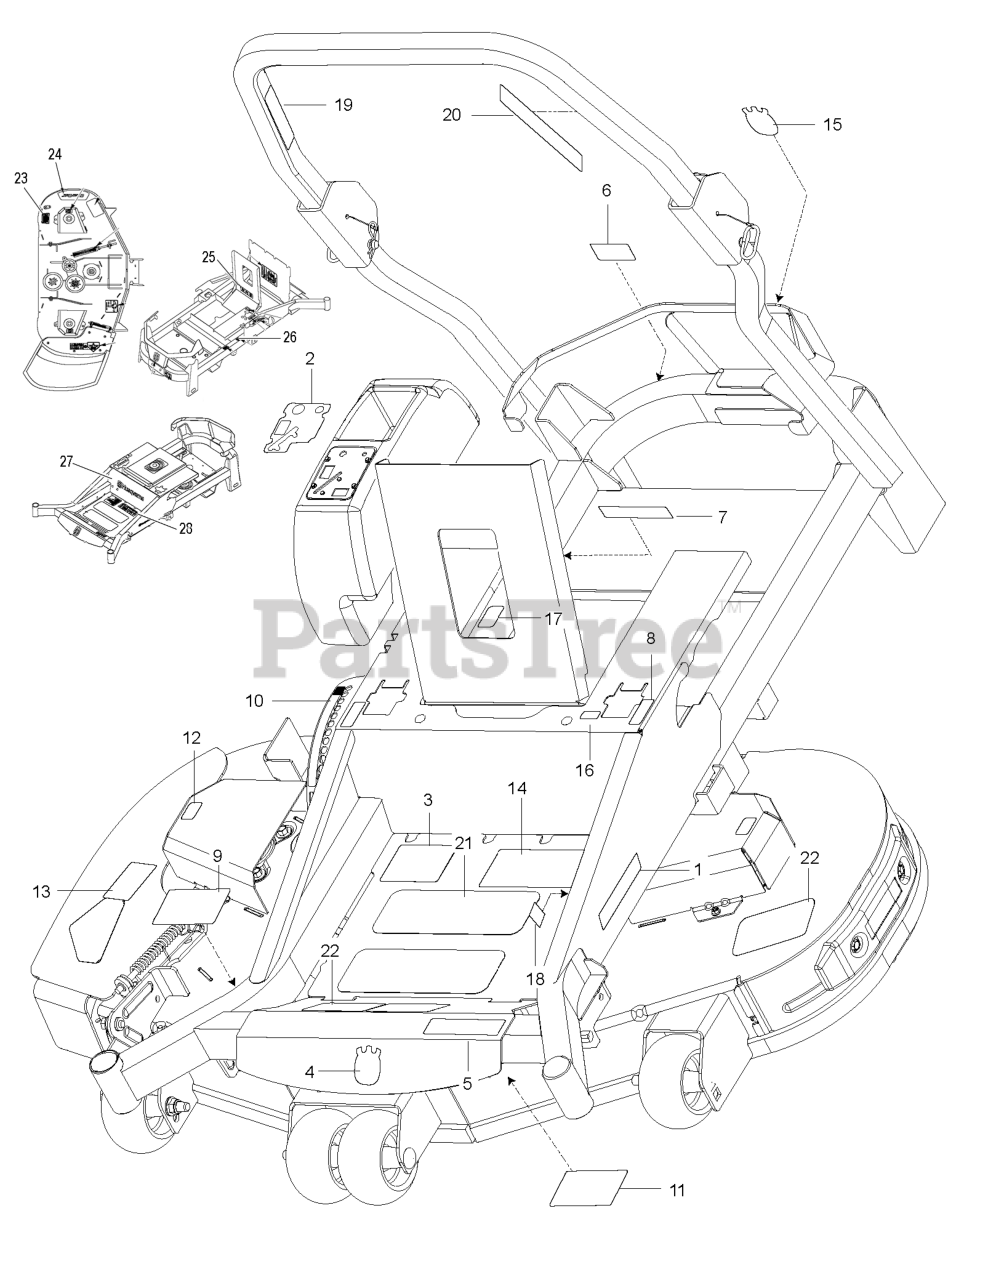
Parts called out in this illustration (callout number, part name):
1	RP.DECAL.BADGE.170MM.TEXTLOGO
2	DECAL, CONSOLE HUS
3	DECAL.ZTR.STRTNGINST.REMOTECHK
4	DECAL.AUGER.HUSQ.CROWN.SNOW
5	DECAL.MZ48
6	DECAL, BELT DRIVE
7	EURO DECAL-BATTERY WARNIN6
8	DECAL.ZTR.MOTCONTRL.SYMBOL.HUS
9	DECAL, BELT ROUTING
10	DECAL, HEIGHT ADJUST
11	DECAL, SERVICE
12	DECAL.DECK.CLEARCUT.NOSTEP
13	DECAL.TRACT/ZTR.DECKWARN.HUSQ
14	DECAL.ZTR.WARNING.SMARTIGNITIN
15	DECAL, CROWN H, 110MM
16	DECAL.STR.S.T.SYSMBOLONLY.2014
17	DECAL CERTIFICATION DECAL EMCC
18	DECAL.80.DBA.AUSTRALIA
19	DECAL, ROPS, WARNING
20	DECAL ROPS
21	ANTI-SKID PAD
23	DECAL DECK DECAL DECAL.DECK.WA
24	DECAL DECK DECAL DECAL.48DECK.
25	EURO DECAL-BATTERY WARNIN6
26	Decals
27	DECAL ZTR BRAND GRAPHIC DECAL.
28	DECAL ZTR WARNING DECAL DECAL.
